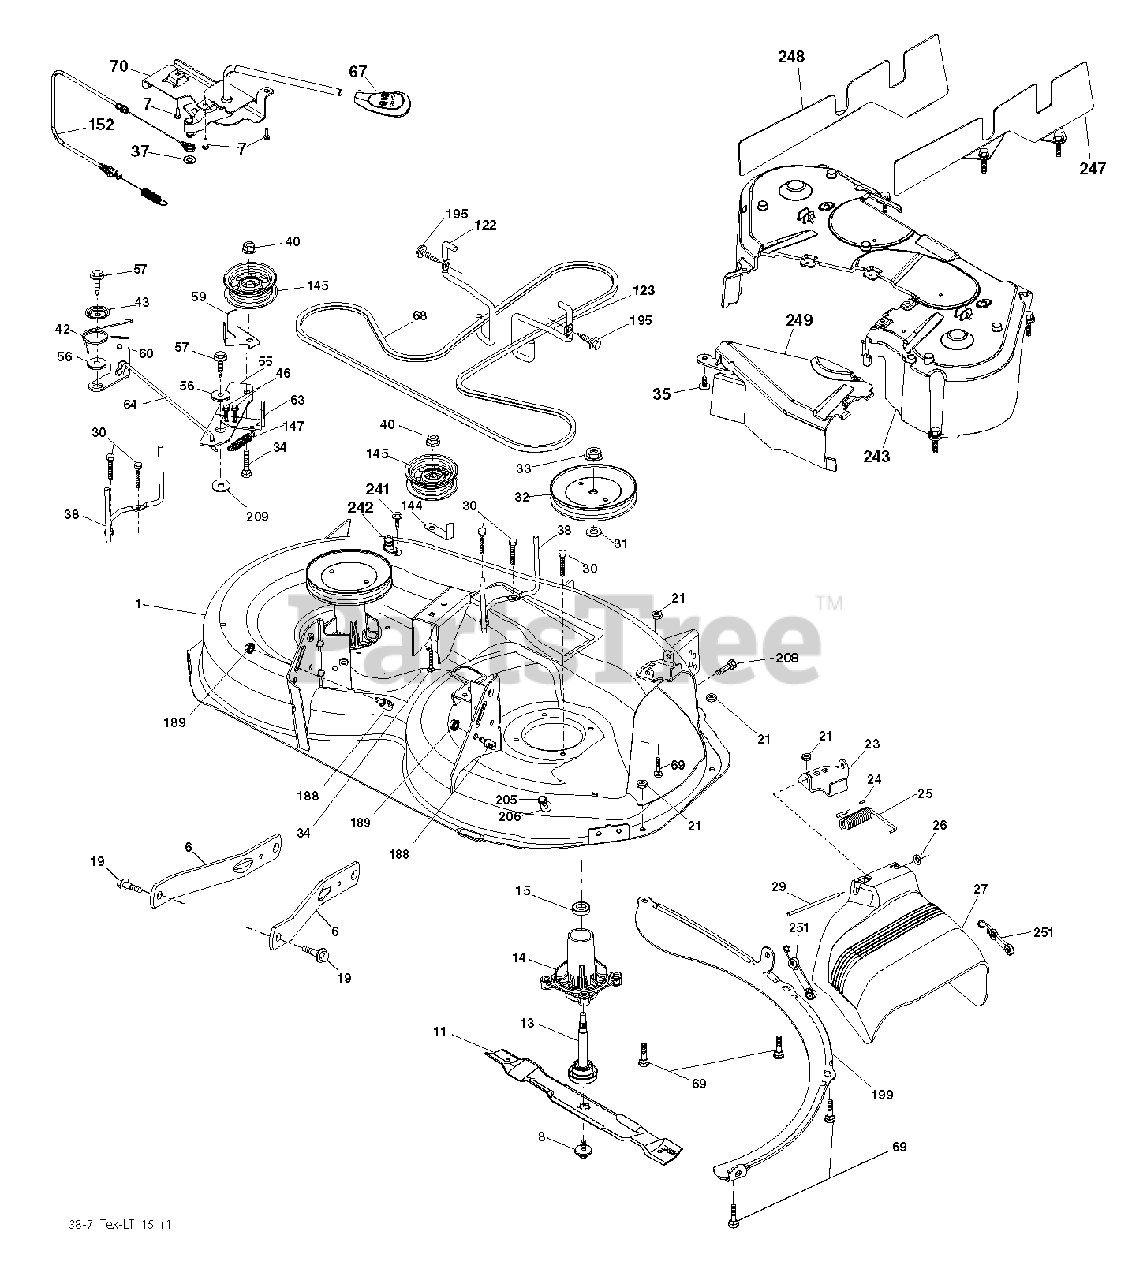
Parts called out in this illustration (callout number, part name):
6	ARM.SUSPENSION.MOWER.R
7	SCREW.#10 X 0.750.BOS THREAD
8	BOLT.WASHER.ASM.7/16-2
11	BLADE 38" PREMIUM
13	SHAFT.ASM.MDRL.N/GREASE.38
14	HOUSING MANDREL
19	BOLT.SHOULDER
21	LOCKNUT
23	BRKT.DEFLECTOR.38"2005+
24	CAP-SLEEVE LT
25	SPRING.TORSION.DEFLECT
26	NUT PUSH M
29	ROD.HINGE
30	SCREW, WASHER HEAD
31	WASHER.SPACER.MANDREL
32	PULLEY.MANDREL.5.0.PD.38"
33	NUT.FLANGE.LOCK.TOP
34	BOLT.3/8-16X1.50
35	FASTENER.XMAS.TREE
38	KEEPER BELT LH MANDREL
40	NUT LOCK FLG 3/8-16 UNC
42	SPRING.TORSION.BRAKE
43	SRPING.TORSION.RETAINE
46	SCREW.1/4-20X5/8
55	IDLER.ARM
56	SPACER.RETAINER
57	SCREW 3/8-16X1
59	GUARD, BELT
60	ARM BRAKE MOWER RH 38"
63	ARM BRAKE MOWER RH
64	LINK BRAKE
67	HANDLE.CLUTCH.CABLE.LT
69	BOLT
70	CLUTCH.ASM.MANUAL.LT.PRED
122	KEEPER BELT ENGINE LH
123	KEEPER BELT RH
144	KEEPER BELT
145	PULLEY.IDLER.48"PRIMARY
147	SPRING RETURN
152	CLUTCH CABLE
188	STUD.FASTNER.W/ANTI-ROTATE
189	NUT LOCK HEX FLANGE 5/16-18
195	SCREW, 3/8-16X3/4
199	BAFFLE VORTEX
205	SCREW
208	SCREW 3/8-16X1/2
209	WASHER 12/32X2X10GA
242	PORT.WASHOUT
